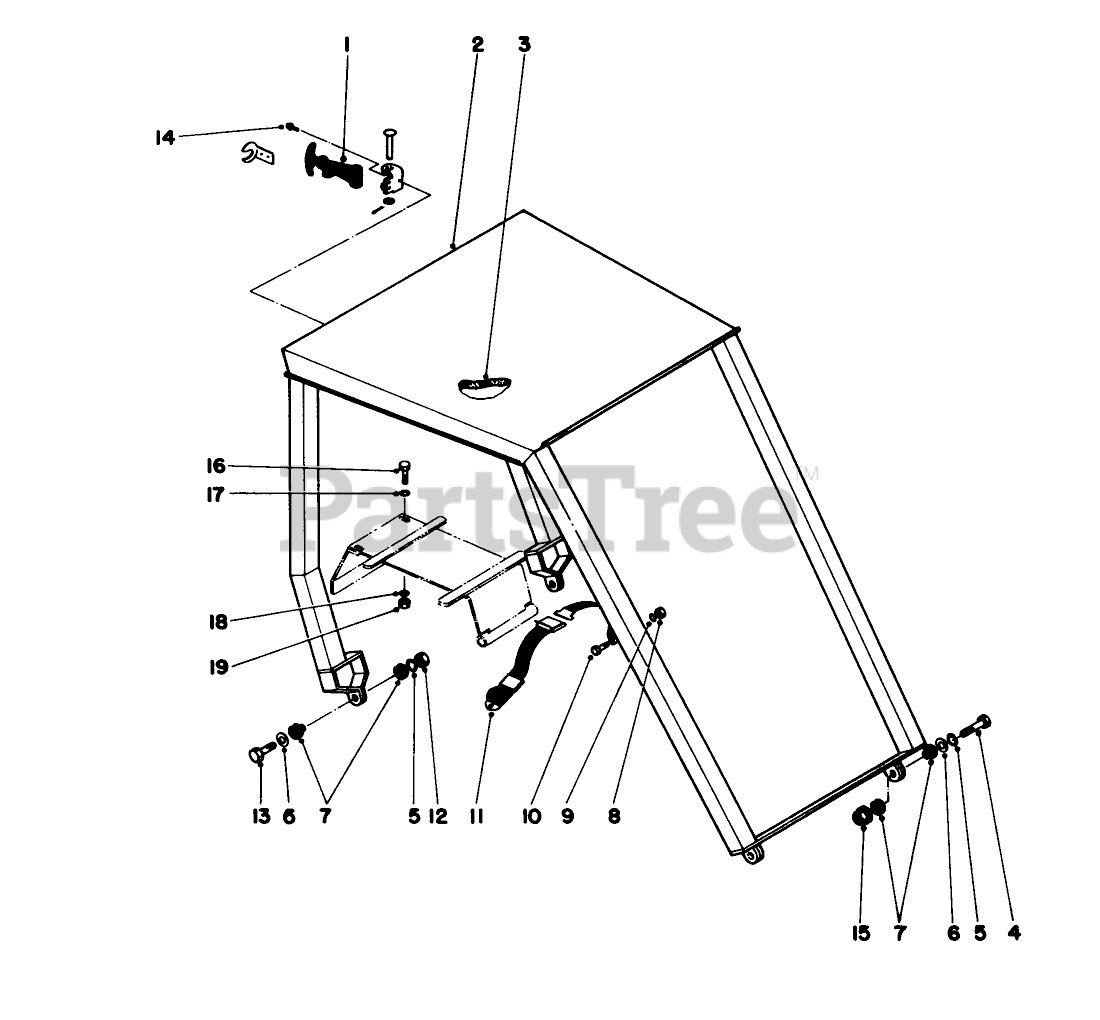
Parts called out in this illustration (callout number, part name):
1	Hood Latch
2	Roll Bar
3	1" Insulation
4	SCREW-HH
5	WASHER-LOCK
6	WASHER-FLAT
7	Rubber Mount
8	NUT-LOCK, NI
9	WASHER-FLAT
10	SCREW-HH
11	SEAT BELT ASM
12	NUT-HEX
13	SCREW-HH
14	SCREW-HWH
15	Front Mount
16	SCREW-HH
17	WASHER-FLAT
18	WASHER-LOCK
19	NUT-HEX
